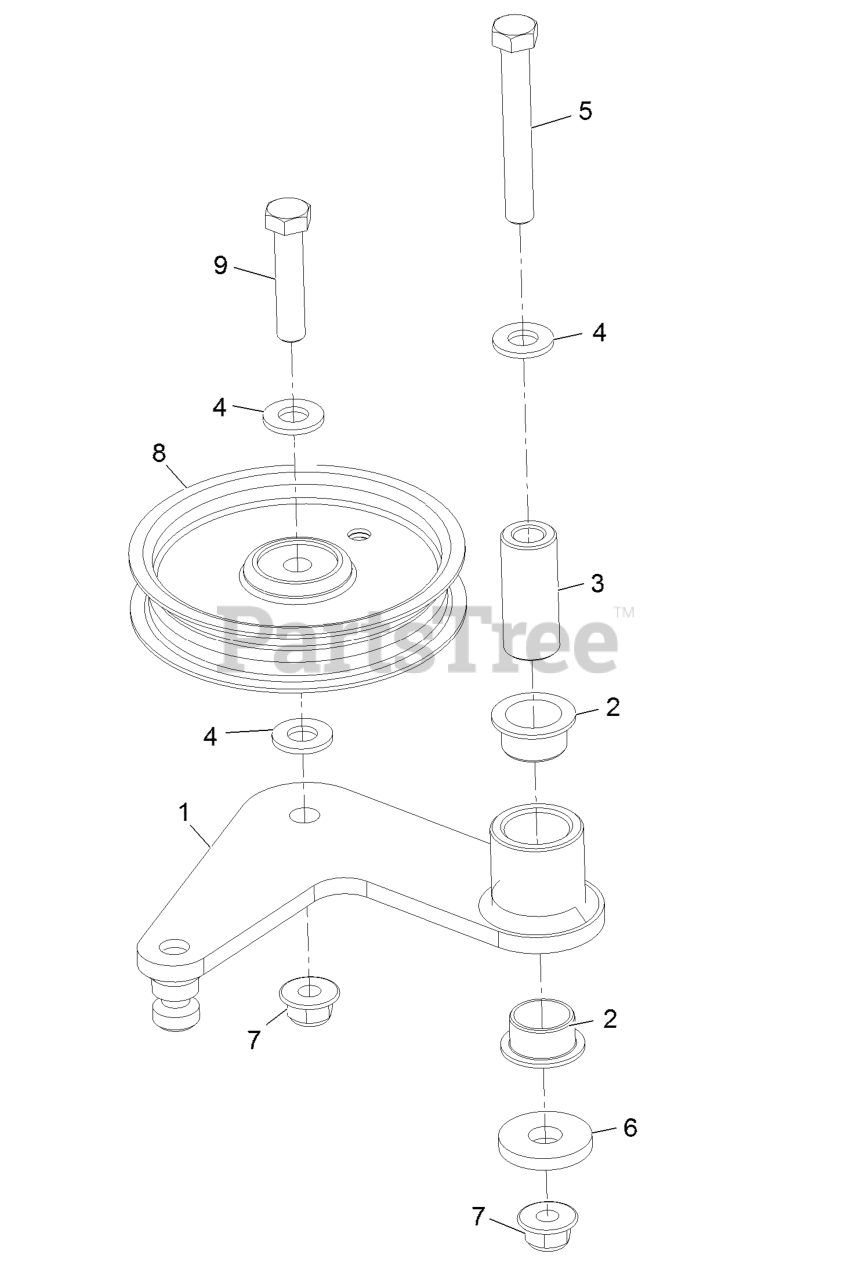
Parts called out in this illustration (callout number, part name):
1	Idler Arm ASM
2	Bushing-Flanged
3	Spacer, Pivot
4	Washer-3/8 SAE
5	Screw-HH 3/8-16 X 2 3/4
7	Nut-Nyloc 3/8-16 Flg
8	Pulley-Idler
9	Screw-HH 3/8-16 X 1 3/4
